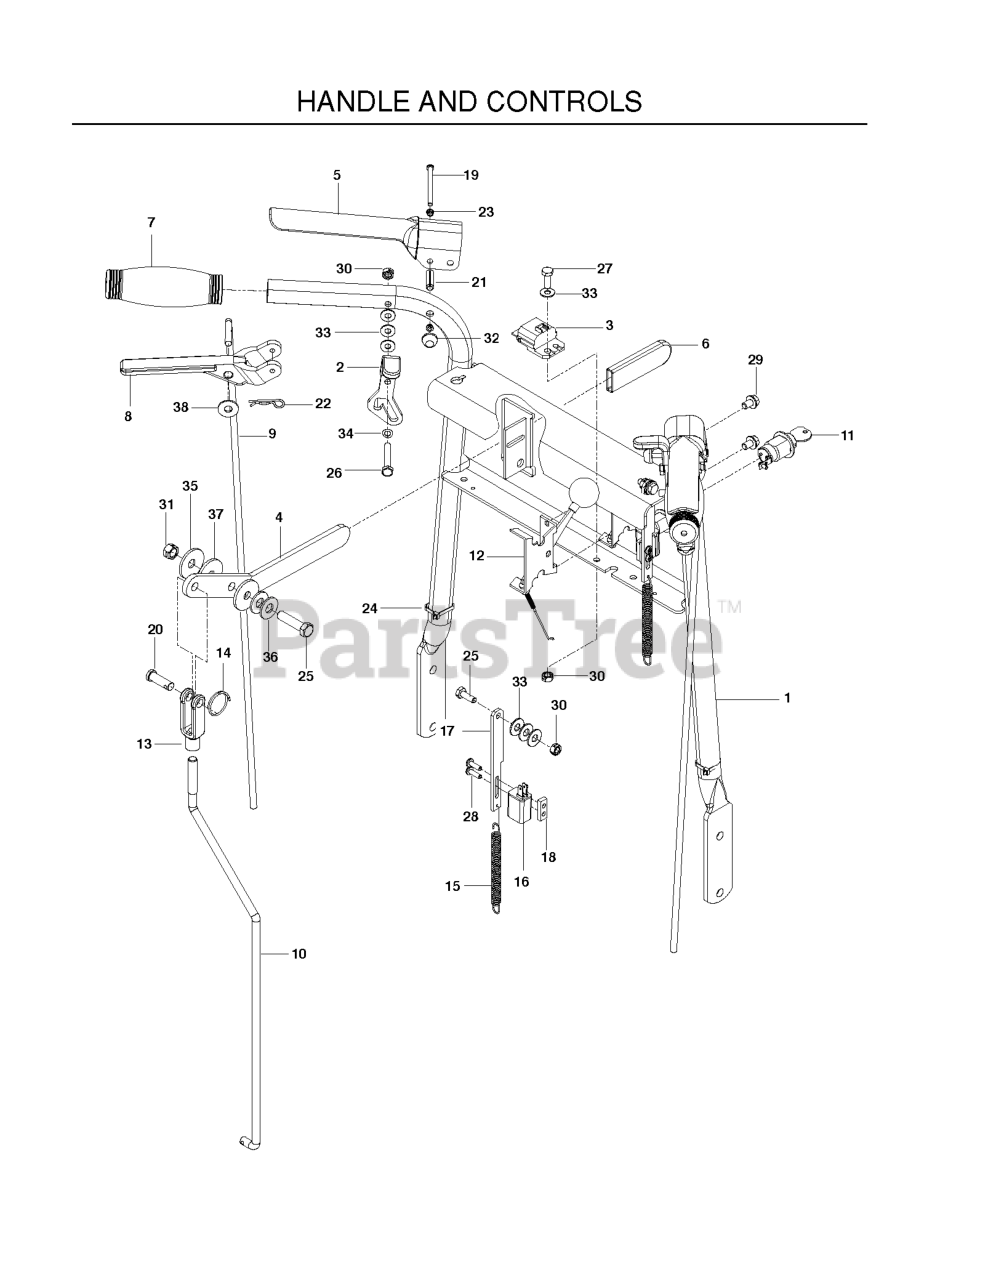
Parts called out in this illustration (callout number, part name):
1	HANDLE, UPPER W/DECALS
2	LATCH LT THUMB W/GRIP
5	LEVER OPC W/GRIP
7	GRIP HANDLE
8	DRIVE LEVER
9	TRACTION ROD
11	KEY SWITCH, COMPLETE
12	THROTTLE CABLE W/ BALL KNOB
13	YOKE-3/8-24 PLTD
17	LINKAGE, O P
18	TAPPED PLATE
19	PIN CLEVIS
20	CLEVIS PIN 3/8 X 1 1/8
21	ROLL PIN 5/16 X 1.125
22	HAIRPIN #2
24	TIE, PLASTIC
25	HCS 3/8C X 1 1/2
26	BOLT 1/4C X 1 3/4
27	HCS 1/4C X 3/4 HCS
28	SCREW #10-24 X 5/8
29	HWST 1/4C X 3/8
30	NUT 1/4C CENTER LOCK
31	NUT 3/8C CENTERBLOCK
33	WASHER 1/4 SAE
34	WASHER, WAVE SPRING
35	CONE WASHER
36	WASHER 3/8 FLAT
37	WASHER, FIBER
38	WASHER 5/16 FLAT
